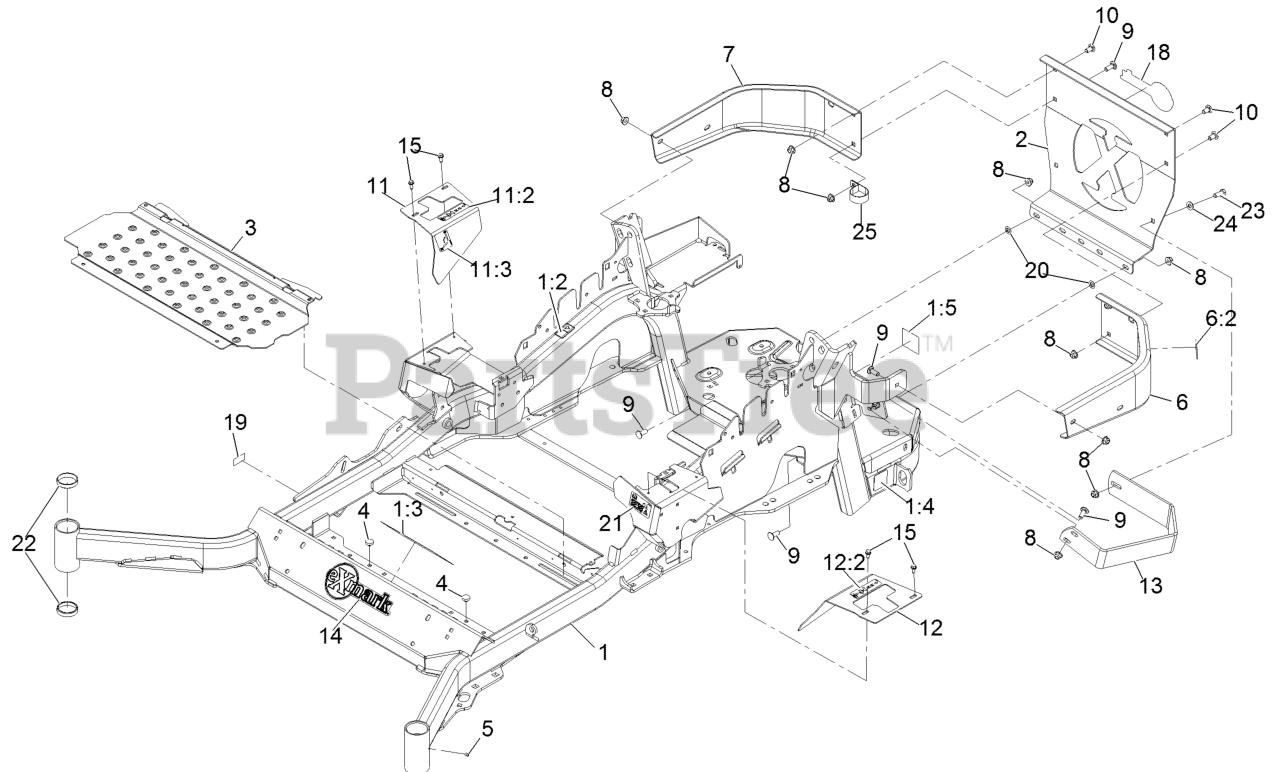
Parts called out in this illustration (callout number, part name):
1	Mainframe ASM
1:2	Decal-Warning
1:3	Decal-Danger
1:4	Decal-Hazard, Pinched Finger
1:5	Decal-Spark Arrester
2	Plate,Rear Guard
6	LH Bumper ASM
6:2	Decal-Warning
7	Bumper-RH
8	Nut-Nyloc 3/8-16 Flg
9	Bolt-Carriage 3/8-16 X 1
10	Bolt-Carriage 3/8-16 X 3/4
11	RH Motion Control Cover ASM
11:2	Decal-Control, Motion
11:3	Decal-Park Brake, CE
12	LH Motion Control Cover ASM
12:2	Decal-Control, Motion
13	Guard-Muffler
14	Decal-Exmark Logo
15	Screw-HWH 1/4-20 X .62
18	Decal-Exmark Logo
19	Decal-Patent
20	Nut-Push 3/8-16
21	Decal-Fuel Fill, CE
22	Cup-Bearing Tapered Roller
23	Screw-HH 3/8-16 X 1
24	Washer-3/8 SAE
